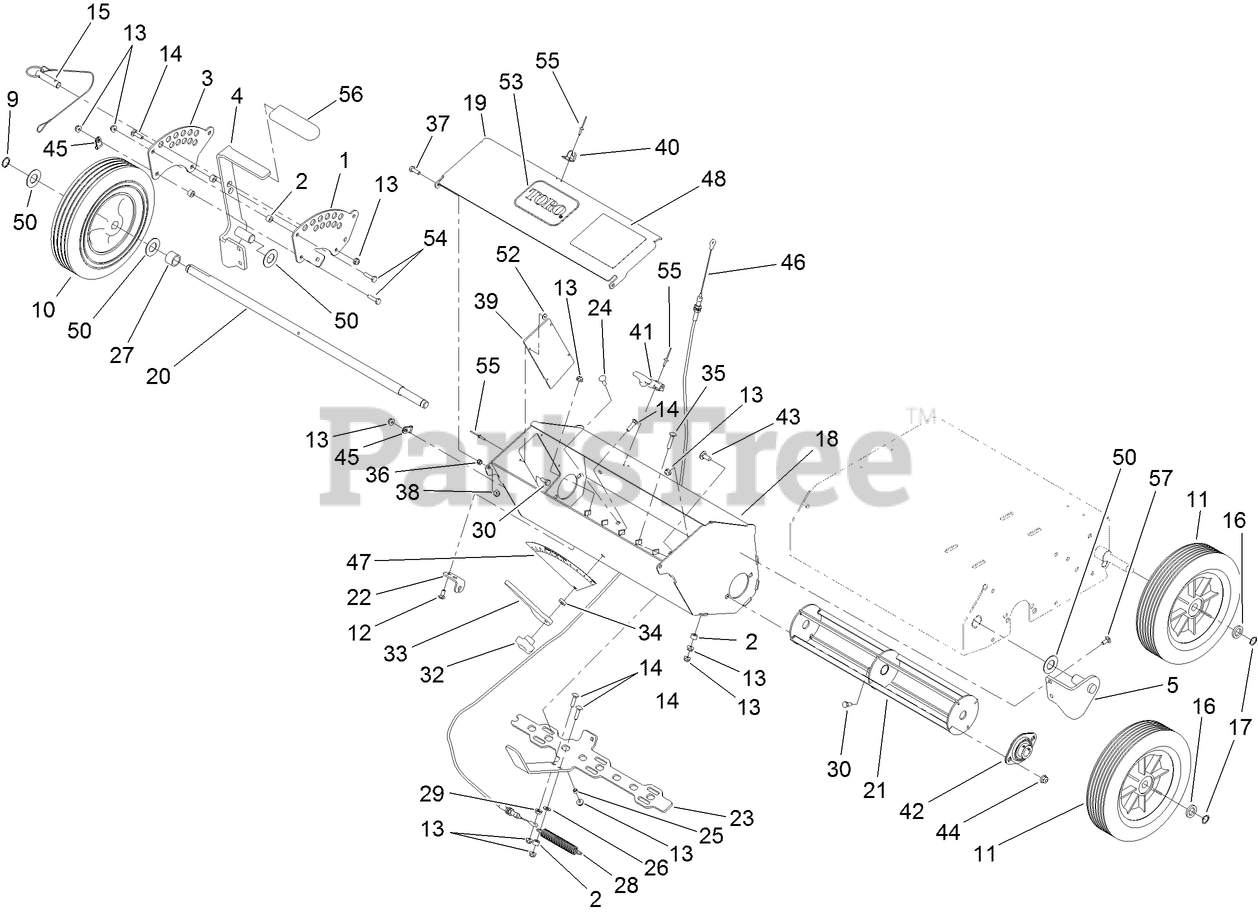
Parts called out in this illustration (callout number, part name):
1	BRACKET
2	SPACER
4	BRACKET-ADJUST, HEIGHT
5	BRACKET-WHEEL
9	Ring-Snap
11	WHEEL-TRANSPORT 10"
12	SCREW-CARR
13	NUT-HF
14	SCREW-CARR
15	PIN-HITCH
16	SPACER-BEARING
17	RING-SNAP, EXTERNAL
18	BOX-SEEDER
19	COVER-SEEDBOX
20	SHAFT-AGITATOR
22	BRACKET-SEED FLOW
23	GATE-SEED
24	BOLT-CARR
25	SPACER
26	WASHER-FLAT
27	SPACER-LOCKUP
28	SPRING-EXTENSION
29	NUT-HF
30	SCREW-HH
32	KNOB-HANDLE
33	GAUGE-SEED FLOW
34	SPACER
35	SCREW-CARR
36	BUSHING-FLANGE, SPLIT
37	SCREW-HH
38	NUT-LOCK, NI
39	WINDOW-SEEDER BOX
40	KEEPER-LATCH, RUBBER
41	LATCH-RUBBER
42	BEARING
43	SCREW-CARR
44	NUT-HF, NI
45	CLAMP-R
46	CABLE-GATE, SEED
47	DECAL-RATE, FLOW
48	DECAL-SEED GRAPH
50	WASHER-FLAT
52	WASHER-BACK
53	DECAL
54	SCREW-HH
55	RIVET-POP
56	GRIP-LEVER
57	BOLT-CARR
